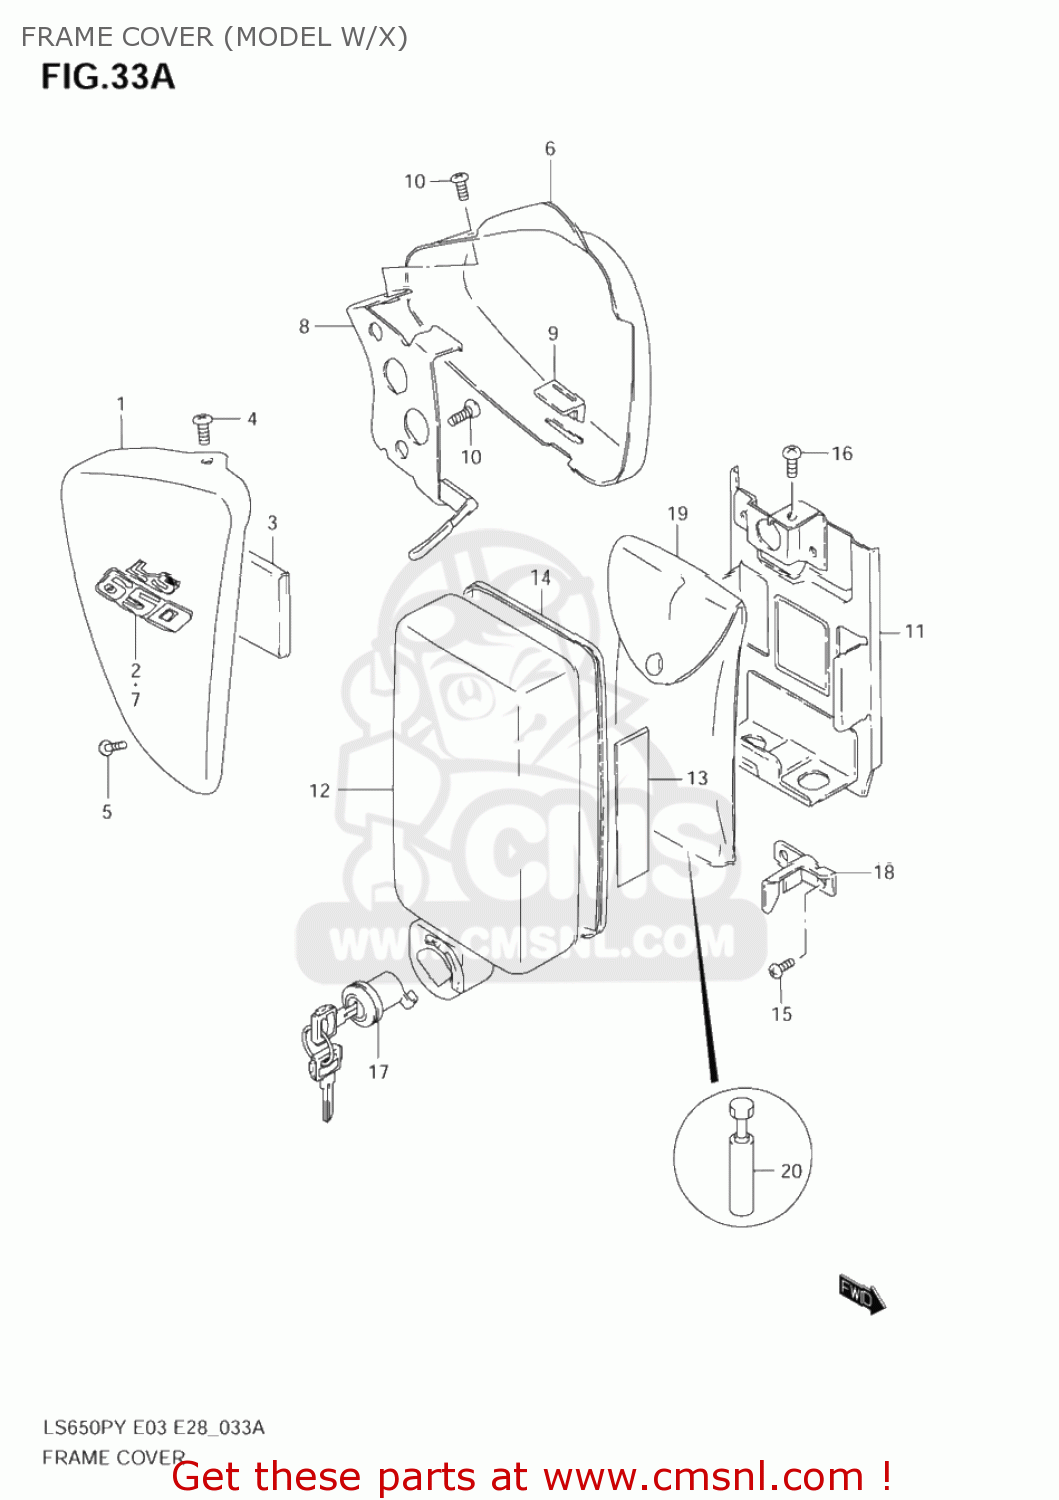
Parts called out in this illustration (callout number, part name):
1	COVER ASSY,FRAME,R(BLACK)
2	EMBLEM,FRAME COVER
3	PAD
4	SCREW
5	SCREW
6	COVER ASSEMBLY,FRAME,LEFT
7	EMBLEM,FRAME COVER
8	BRACKET,FRAME COVER,L
9	CUSHION,FRAME COVER
10	SCREW
11	HOLDER,TOOL
12	COVER COMP,TOOL HOLDER
13	PROTECTOR(80X80X2)
14	MOLDING
15	SCREW
16	SCREW
17	LOCK SET,TOOL HOLDER
18	PLATE,TOOL HOLDER LOCK
19	TOOL ASSY
20	GAUGE ASSY,TENSION
